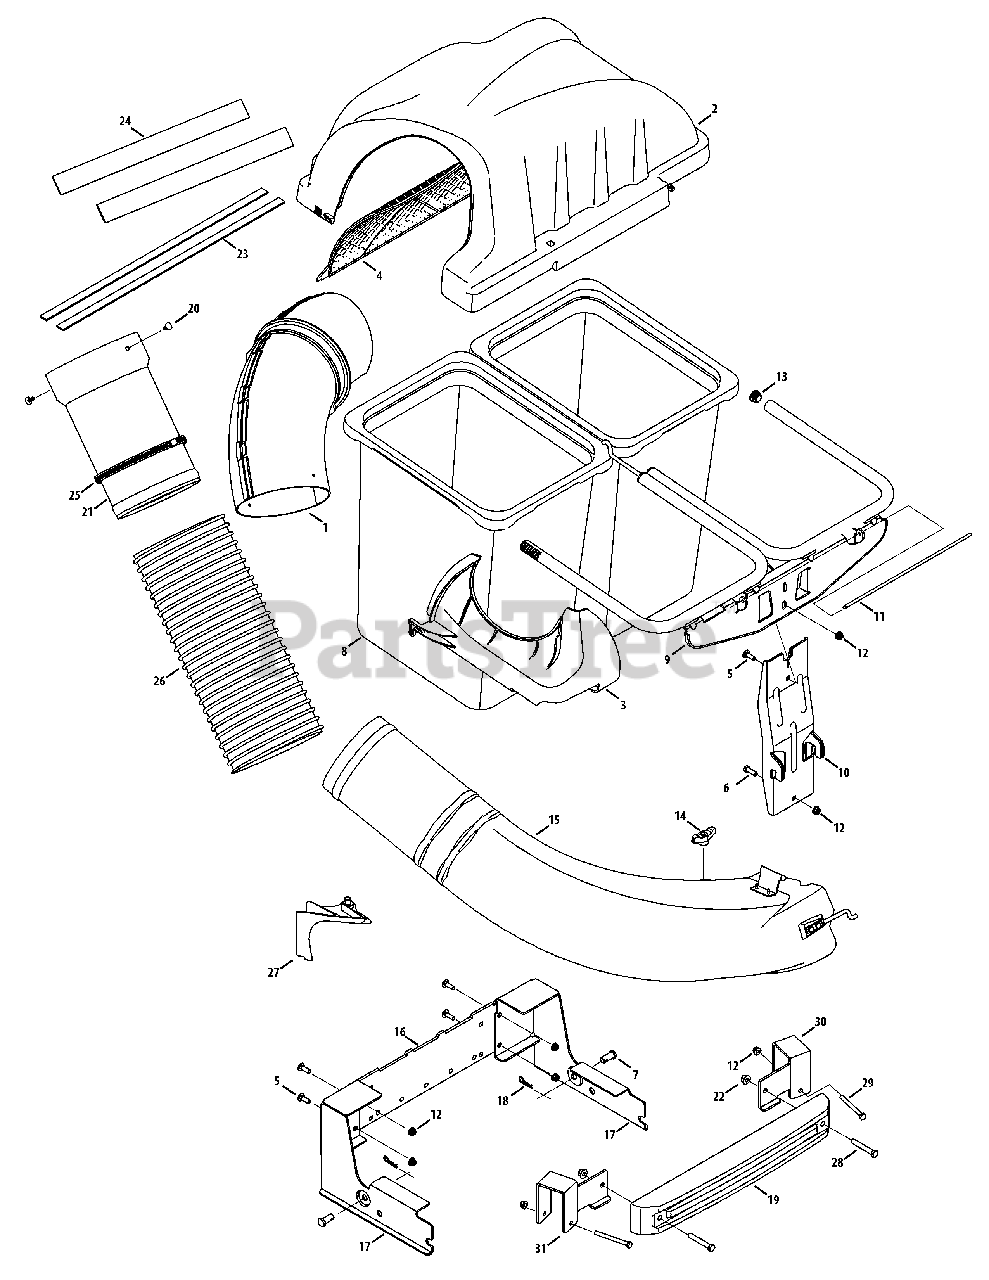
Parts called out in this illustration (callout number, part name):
1	Upper Chute Assembly
2	Twin Bagger Cover
3	Upper Chute Support
4	Bagger Cover Screen
5	Carriage Screw, 5/16-18 x 1.00"
6	Hex Head Screw, 5/16-18 x .75"
7	Clevis Pin, .50" Dia. x .78 Lg.
8	Grass-bag Assembly
9	Twin Bag Support Assembly
10	Vertical Support Bracket
11	Cover Hinge Pin
12	Flange Lock Nut, 5/16-18
15	Discharge Chute Elbow
16	Universal Mounting Bracket
17	RZT Mounting Assembly
18	Cotter Pin, .080 x 1.5625 Internal
19	RZT Bagger Weight
20	Ratchet Clip, .250
21	Bagger Chute Adapter, 7 In.
22	Flange Lock Nut, 3/8 - 16
23	Adhesive Strip
24	Wide Adhesive Rubber Strip
25	Adj. Hose Clamp
26	Flexible Chute Extension
27	Adapter 50"/54" (Stamped Decks)
28	Hex Bolt, 3/8 - 16 x 2.50
29	Hex Bolt, 5/16 - 18 x 2.50
30	Weight Mounting Bracket, LH
31	Weight Mounting Bracket, RH
